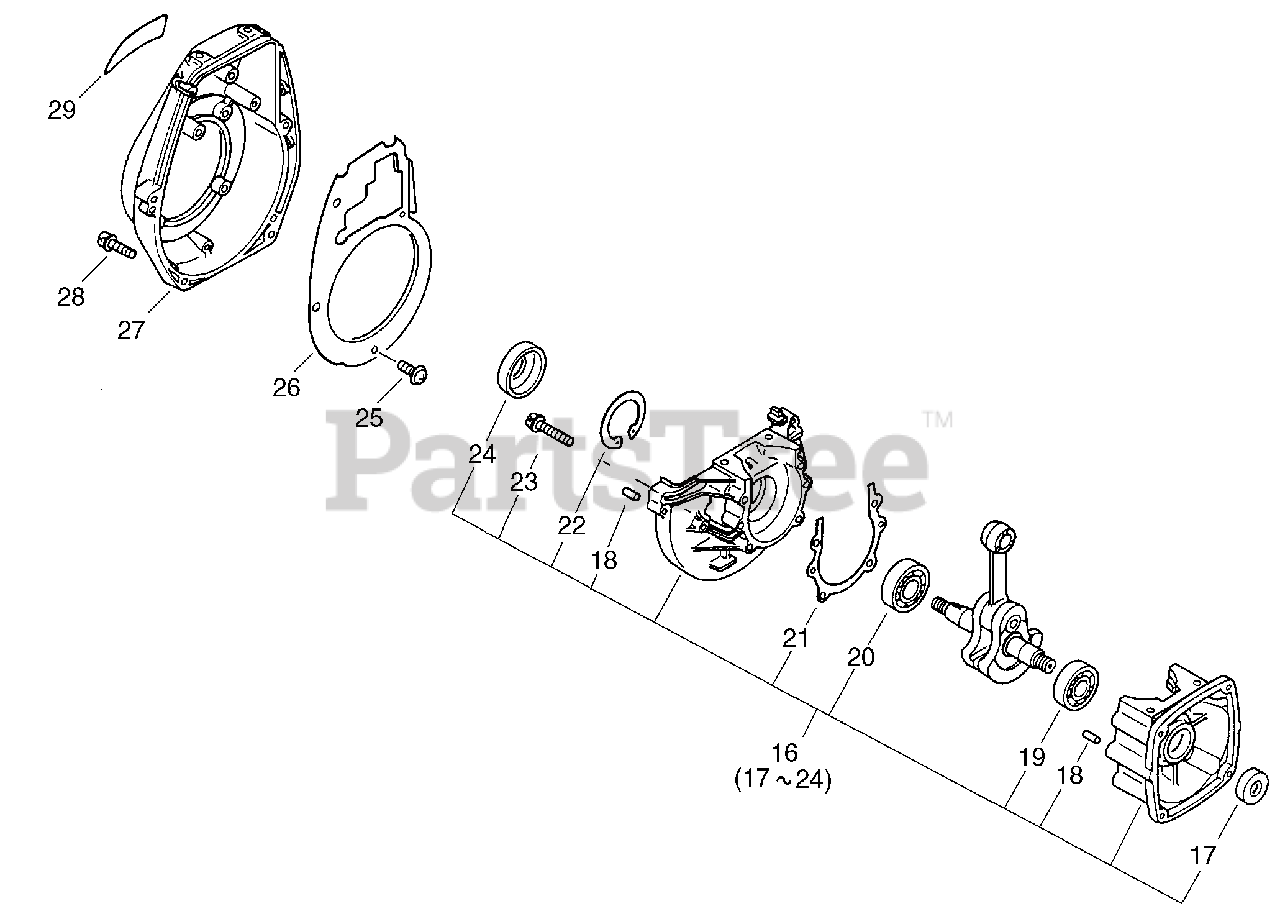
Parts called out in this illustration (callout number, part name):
16	CRANKCASE KIT
17	SEAL, OIL 12
18	PIN, LOCATING 5×10
19	BEARING, BALL - 6201 C3
20	BEARING, BALL 6202
21	GASKET, CRANKCASE
22	RING, SNAP 35
23	BOLT 5×30
24	SEAL, OIL 18
25	SCREW 4×10
26	GUIDE, AIR
27	COVER, FAN
28	BOLT 5×25
29	LABEL - MODEL SRM-4605
